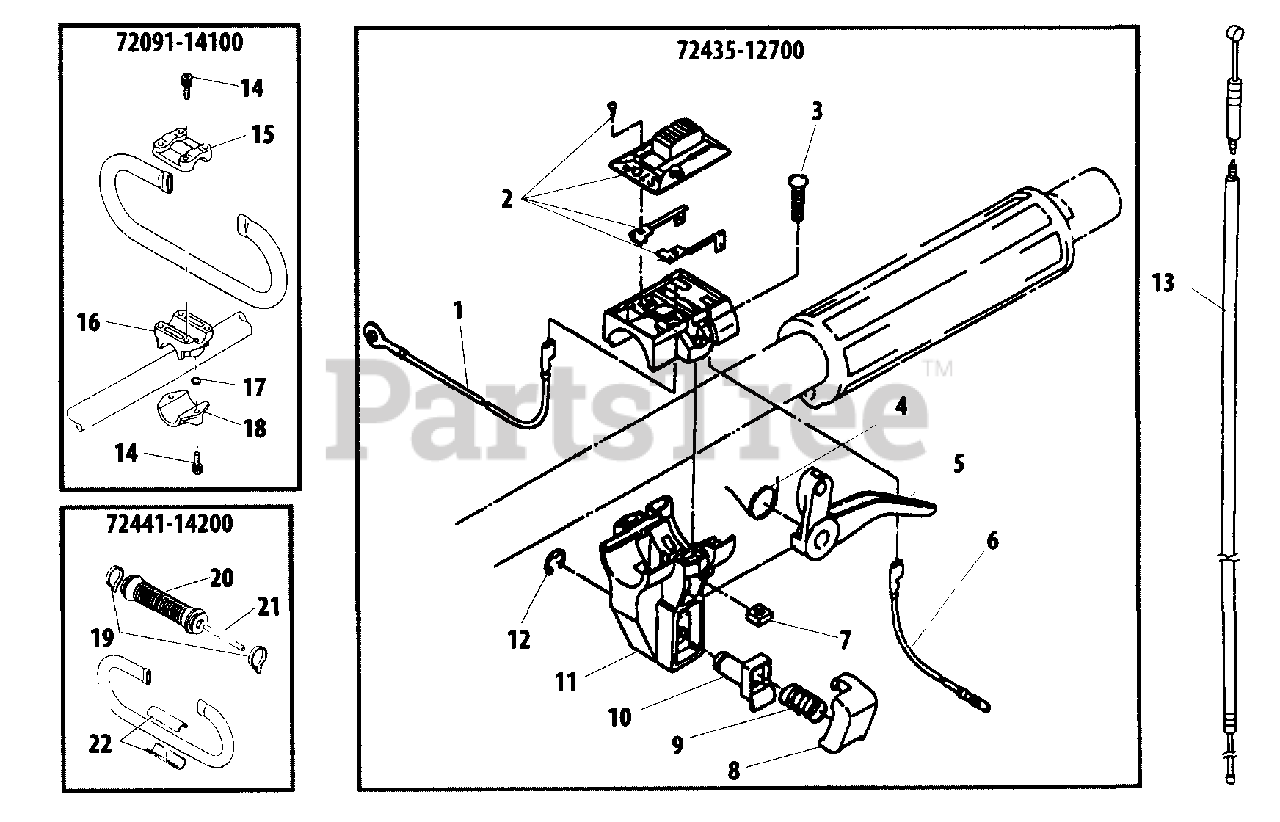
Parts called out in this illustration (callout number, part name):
1	LEAD - BLACK
2	SWITCH ASSY, ON-OFF
3	BOLT
4	SPRING, RETURN
5	TRIGGER, THROTTLE
6	LEAD - RED
7	NUT, THROTTLE LEVER
8	BUTTON, THROTTLE LOCK
9	SPRING
10	LOCKOUT, THROTTLE
11	BODY, THROTTLE CONTROL
12	RING, SNAP
13	CABLE, THROTTLE
14	BOLT M5×25
15	BRACKET, UPPER
16	BRACKET, HANDLE
17	WASHER, FLAT 5.5×10×0.8
18	CLAMP, LOWER
19	BAND
20	GRIP
21	CORE, GRIP
72091-14100	BRACKET ASSY, HANDLE
72435-12700	THROTTLE CONTROL ASSY
72441-14200	HANDLE ASSY, FRONT
